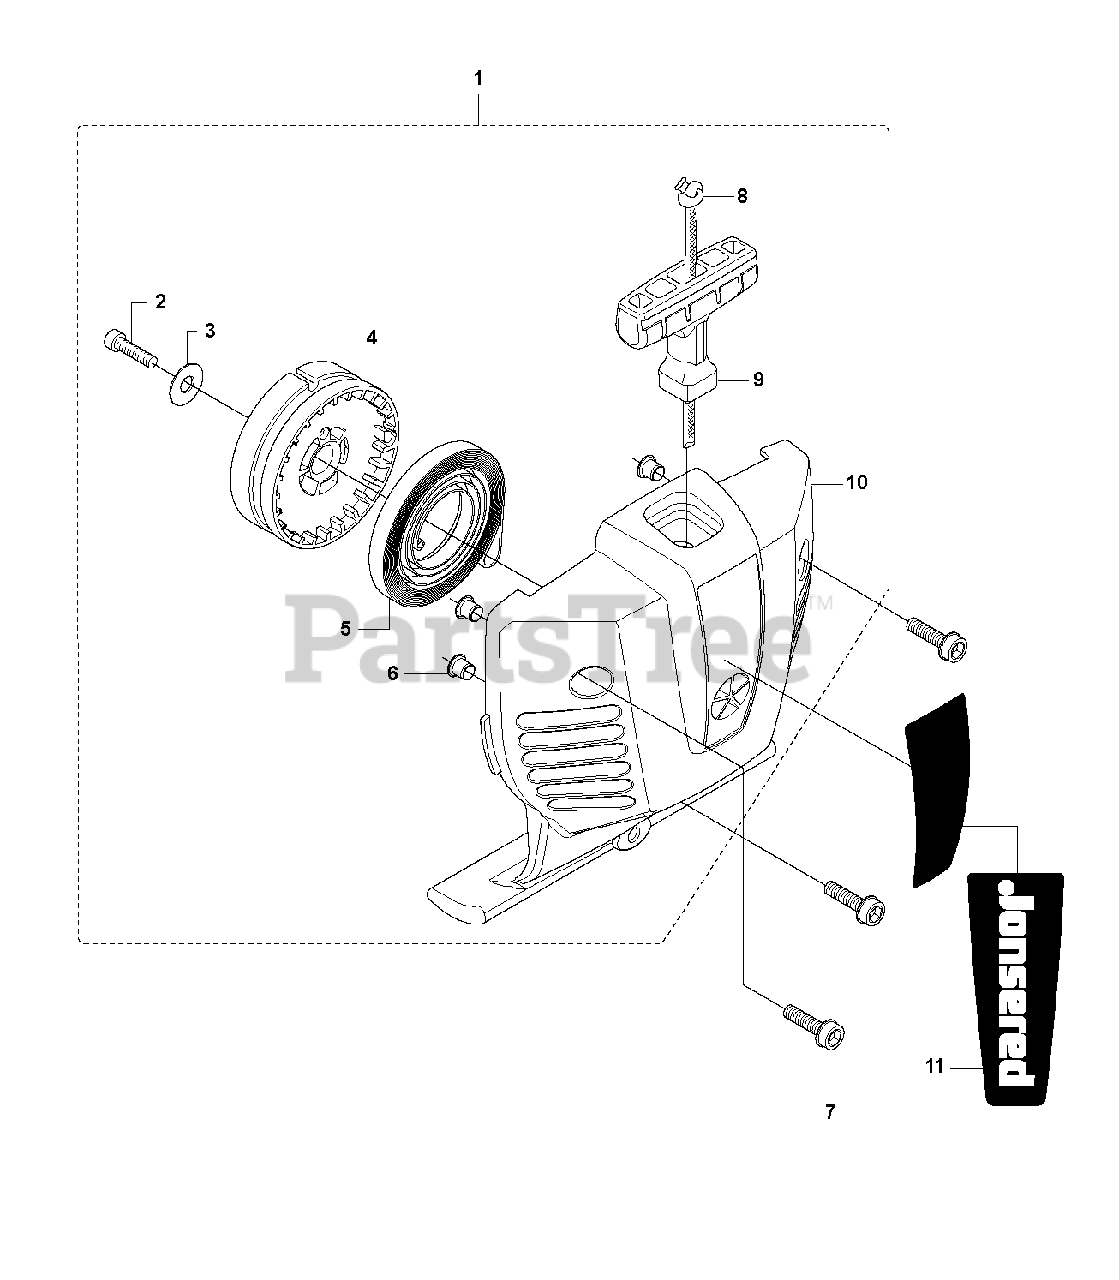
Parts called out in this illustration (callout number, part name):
1	STARTER HOUSING
2	SCREW
3	WASHER
4	%STARTER PULLEY
5	STARTER SPRING
6	SLEEVE
8	STARTER ROPE
9	HANDLE
